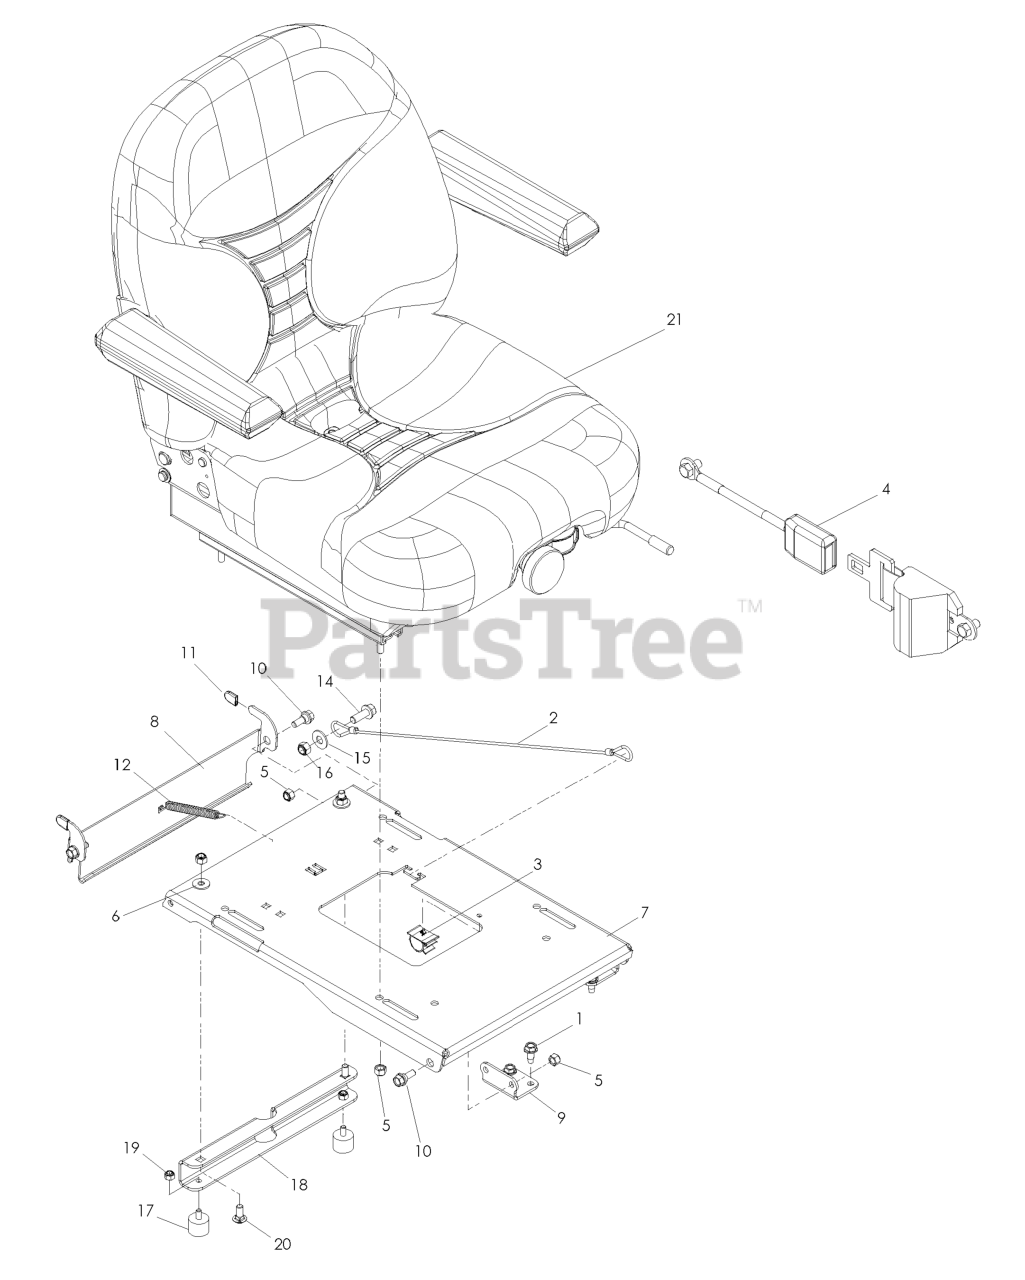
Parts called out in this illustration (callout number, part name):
1	BOLT 5/16-18 X 3/4
2	SEAT LANYARD
3	PUSH-MOUNT WIRE CLIP
4	SEAT BELT, RETRACTABLE
5	NUT 5/16 NYLOC
6	WASHER 5/16 FLAT
7	PAN, SEAT - BLACK
8	LATCH, SEAT - BLACK
9	PIVOT, SEAT PAN
10	SB 5/16-18 HEX HD GD5, BLK ZN
11	GRIP, VINYL, .09 X .495 X.75
13	HCS 5/16C X 1
14	4CS 3/8C X 1 SERRATED HEAD
15	WASHER 3/8 FLAT
16	NUT 3/8-16 NYLOC
17	STUD/PLATE MOUNT
18	STANDOFF, SEAT PAN
19	NUT.1/4-20.HEX.NYLOC.ZD
20	BOLT 5/16C X 3/4" CARRIAGE
21	SEAT - SUSP, NC SWITCH
